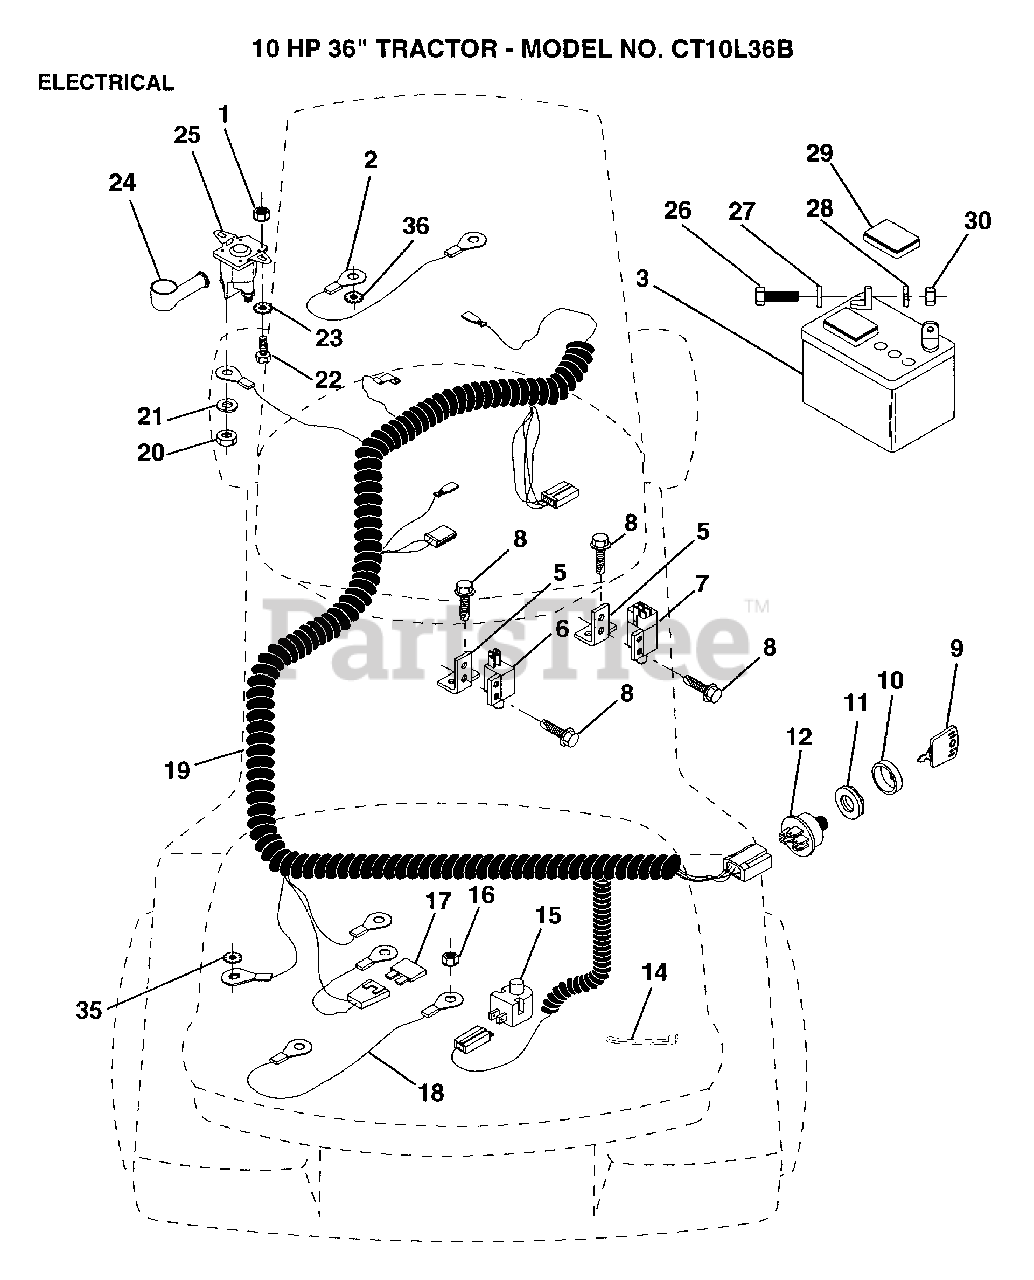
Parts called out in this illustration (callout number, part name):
1	NUT
2	CABLE ASM.
5	BRACKET LT
6	SWITCH-INTER. GT
7	SWITCH INTERLOCKT
8	SCREW
9	KEY
11	NUT IGNITION
14	WIRE TIE
15	SWITCH SEAT
17	FUSE HYT
18	CABLE ASSY
20	NUT
22	BOLT
26	BOLT LT
27	WASHER
28	LOCKWASHER
29	"CAP,BATTERY "
35	LOCKWASHER
36	LOCKWASHER
